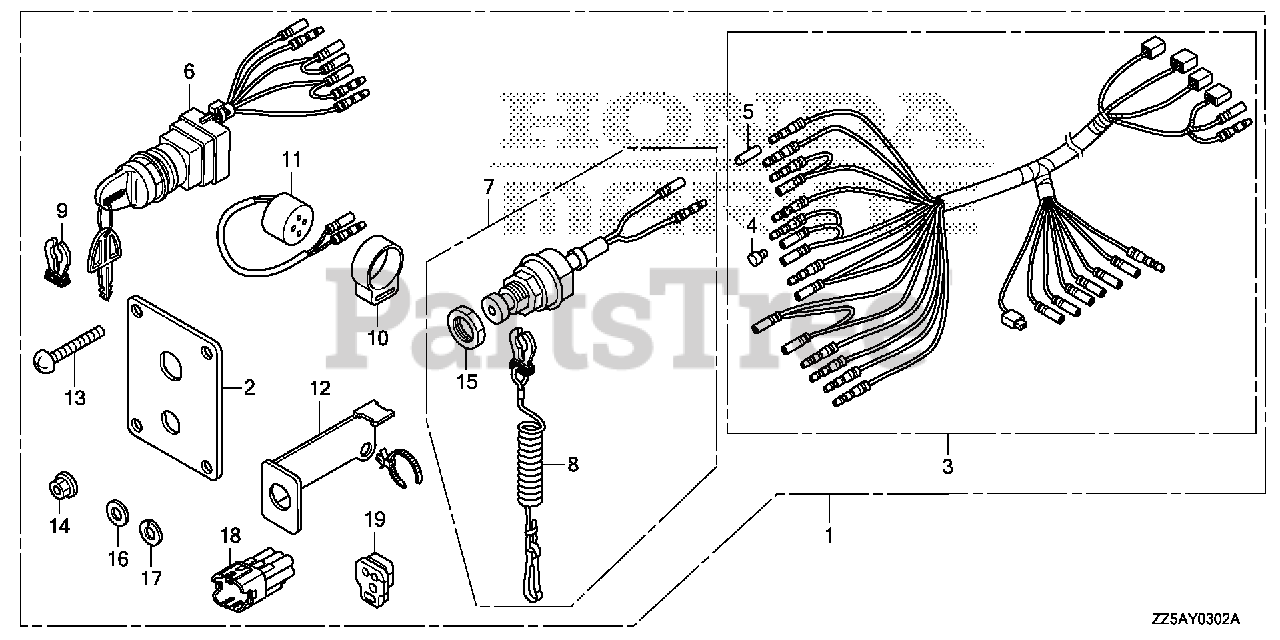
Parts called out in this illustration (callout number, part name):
1	PANEL KIT, SWITCH (SINGLE)
2	PANEL, CONTROL (SINGLE)
3	HARNESS ASSY., SWITCH PANEL
4	PLUG, CONNECTOR (INNER)
5	PLUG, CONNECTOR (OUTER)
6	SWITCH ASSY., COMBINATION
7	SWITCH ASSY., EMERGENCY STOP (SINGLE)
8	WIRE, EMERGENCY
9	CLIP, EMERGENCY LOCK
10	SUSPENSION, AUDIBLE PILOT
11	BUZZER, WARNING
12	BRACKET
13	SCREW, PAN (5X40)
14	NUT, FLANGE (5MM)
15	NUT
16	WASHER, PLAIN (5MM)
17	WASHER, SPRING (5MM)
18	DUMMY, WATERPROOF CONNECTOR (GREEN)
19	GROMMET, CASE (LOWER) (A)
